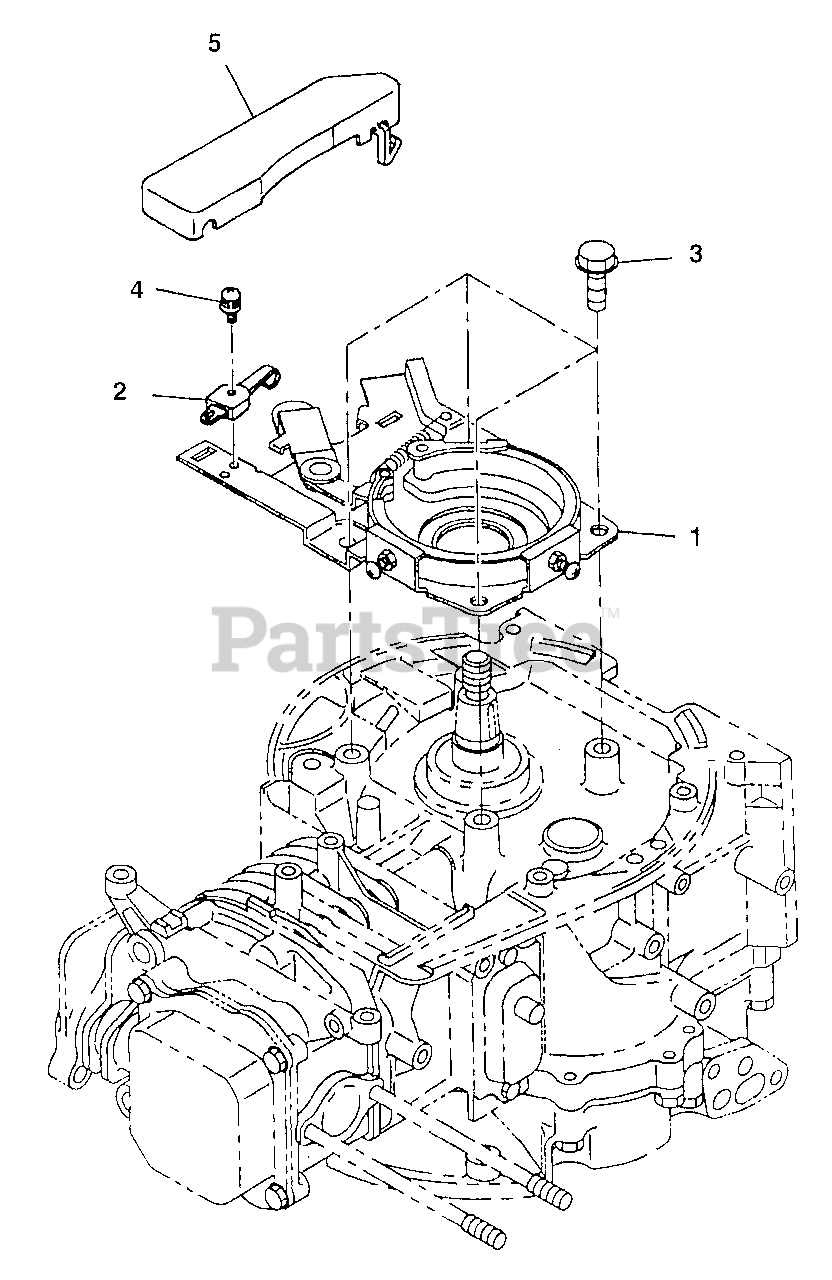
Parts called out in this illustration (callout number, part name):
2	SWITCH, Stop
3	BOLT, Flange
4	SCREW AND WASHER
5	COVER, Stop Switch
